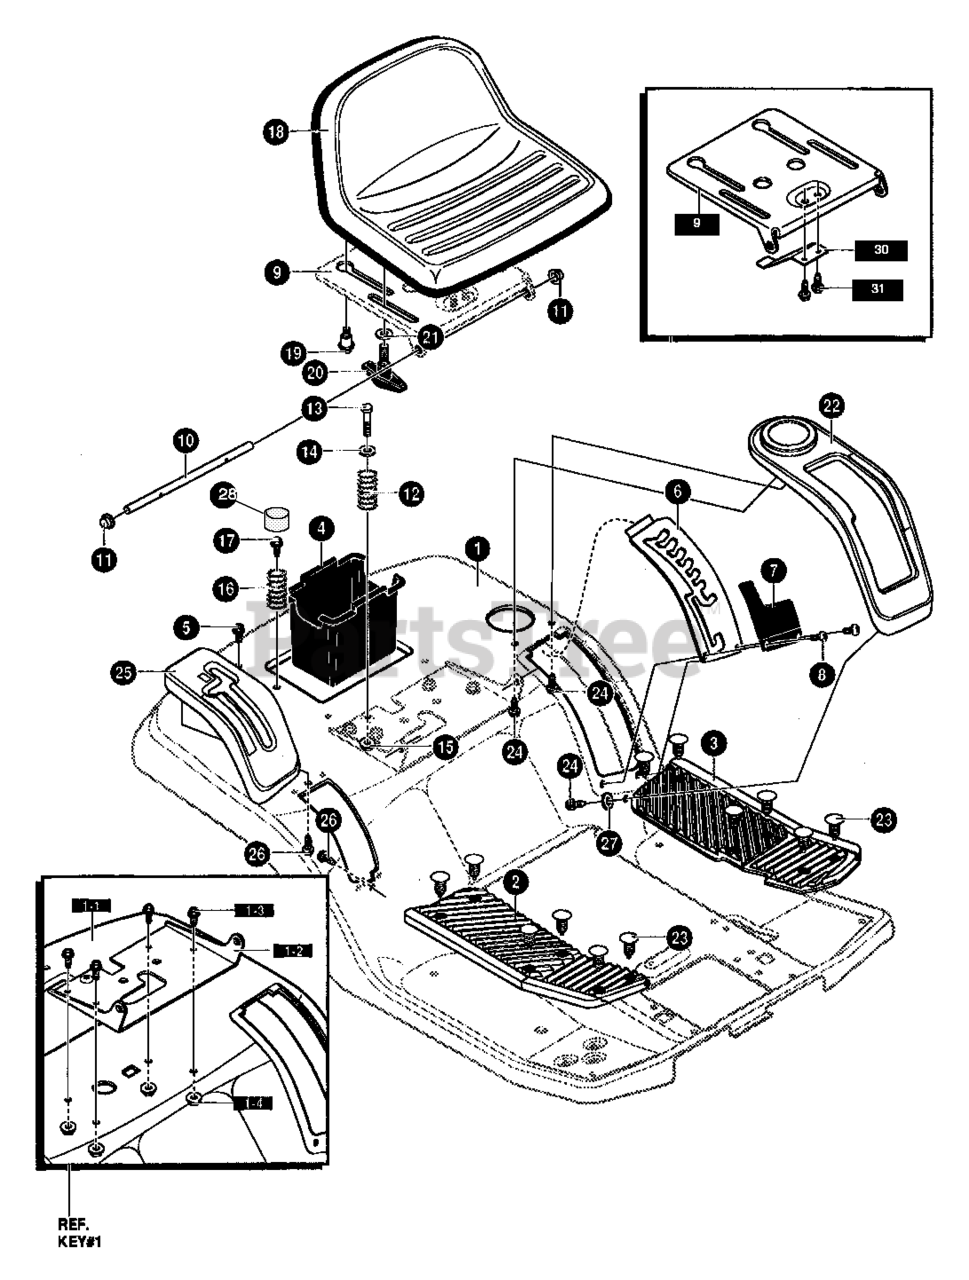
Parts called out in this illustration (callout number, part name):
1	LARGE SEAT DECK
1-1	SEAT DECK, LARGE
1-2	BRACKET, PIVOT SEAT
1-3	SCREW, 5/16-18 x 0.75
1-4	NUT, 5/16-18
2	FOOT REST PAD RH
3	FOOT REST PAD LH
4	CONTAINER, BATTERY
5	SCREW 1/4-20X.63
6	PLATE, LIFT DETENT
7	COVER, LIFT DETENT
9	SUPPORT, SEAT
10	HINGE SEAT PIVOT
11	NUT, PUSH CAP
12	SPRING, COMPRESS
13	BOLT, SHOULDER 1/4-20
14	WASHER CUP
15	NUT, 1/4-20
16	SPRING, COMPRESS
17	SCREW 5/16-18X.75
19	BOLT, SHOULDER 5/16-18
20	BOLT, WING 5/16-18X.50
21	Washer
22	COVER, DETENT PLATE
23	FASTENER, RATCHET
24	SCREW, 1/4-15X.44/.53
25	COVER, HAND/FOOT, HYDRO
26	SCREW, 1/4-15X.44/.53
27	FLATWASHER
30	SPRING, LEAF
31	SCREW, 1/4-20X.50
